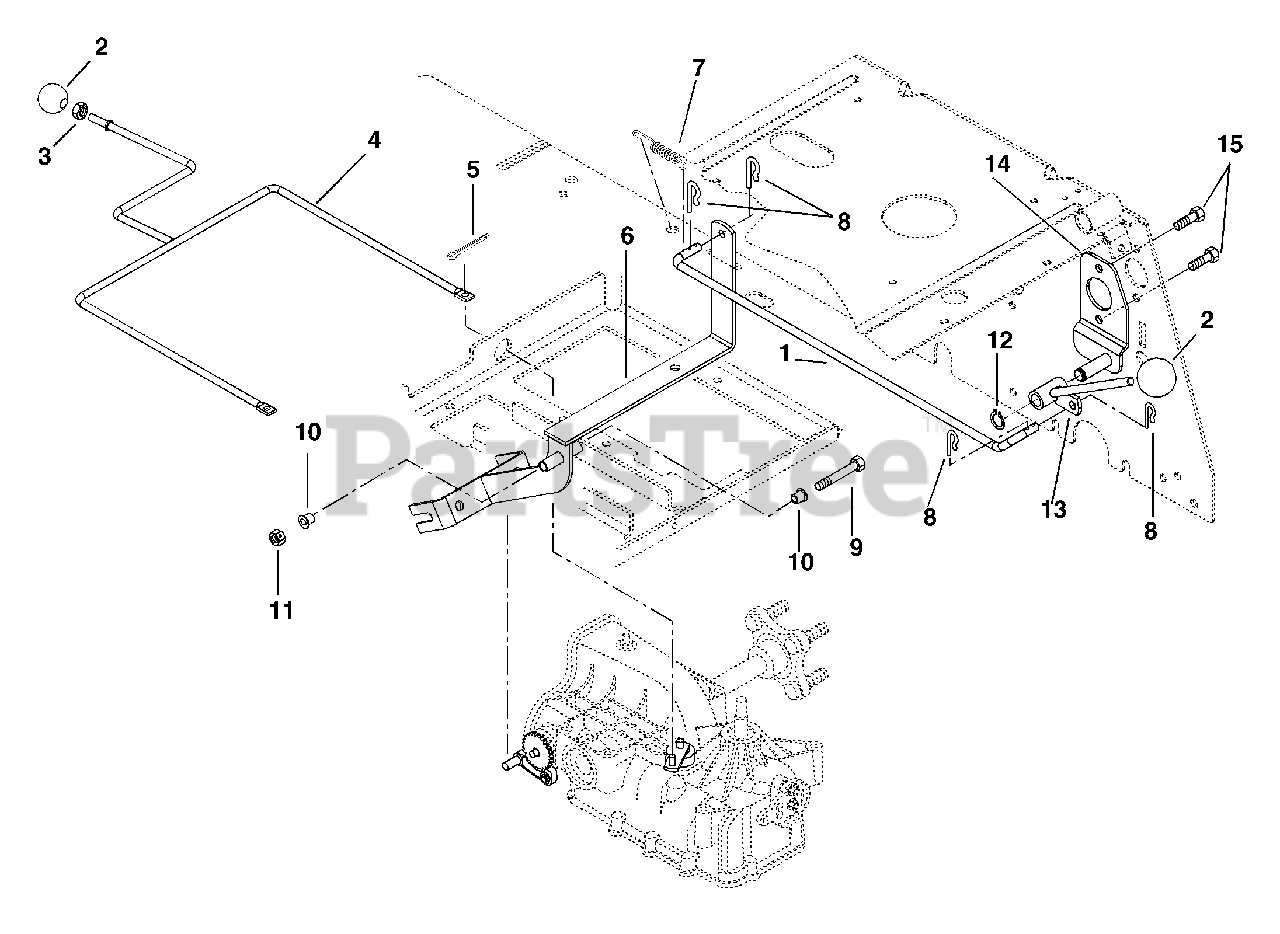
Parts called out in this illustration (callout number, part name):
1	Rod-Brake
3	Nut-Hex .31-18
4	Dump Valve Weldment
5	Pin-Cotter .09 x .75
6	Brake Arm Weldment
7	Spring-Tension .051 x .60 x 2.25
8	Pin-Hair Internal .08 x .18 x 1.18
9	Bolt-Hex .25-20 x 3.00
10	Bushing-Flange .257 x .38 x 1.080
11	Nut-Locking-Center .25-20
12	Ring-Retaining External
13	Lever-Brake
14	Pivot-Brake Lever
15	Bolt-Hex .31-18 x 1.00 Grade 5
